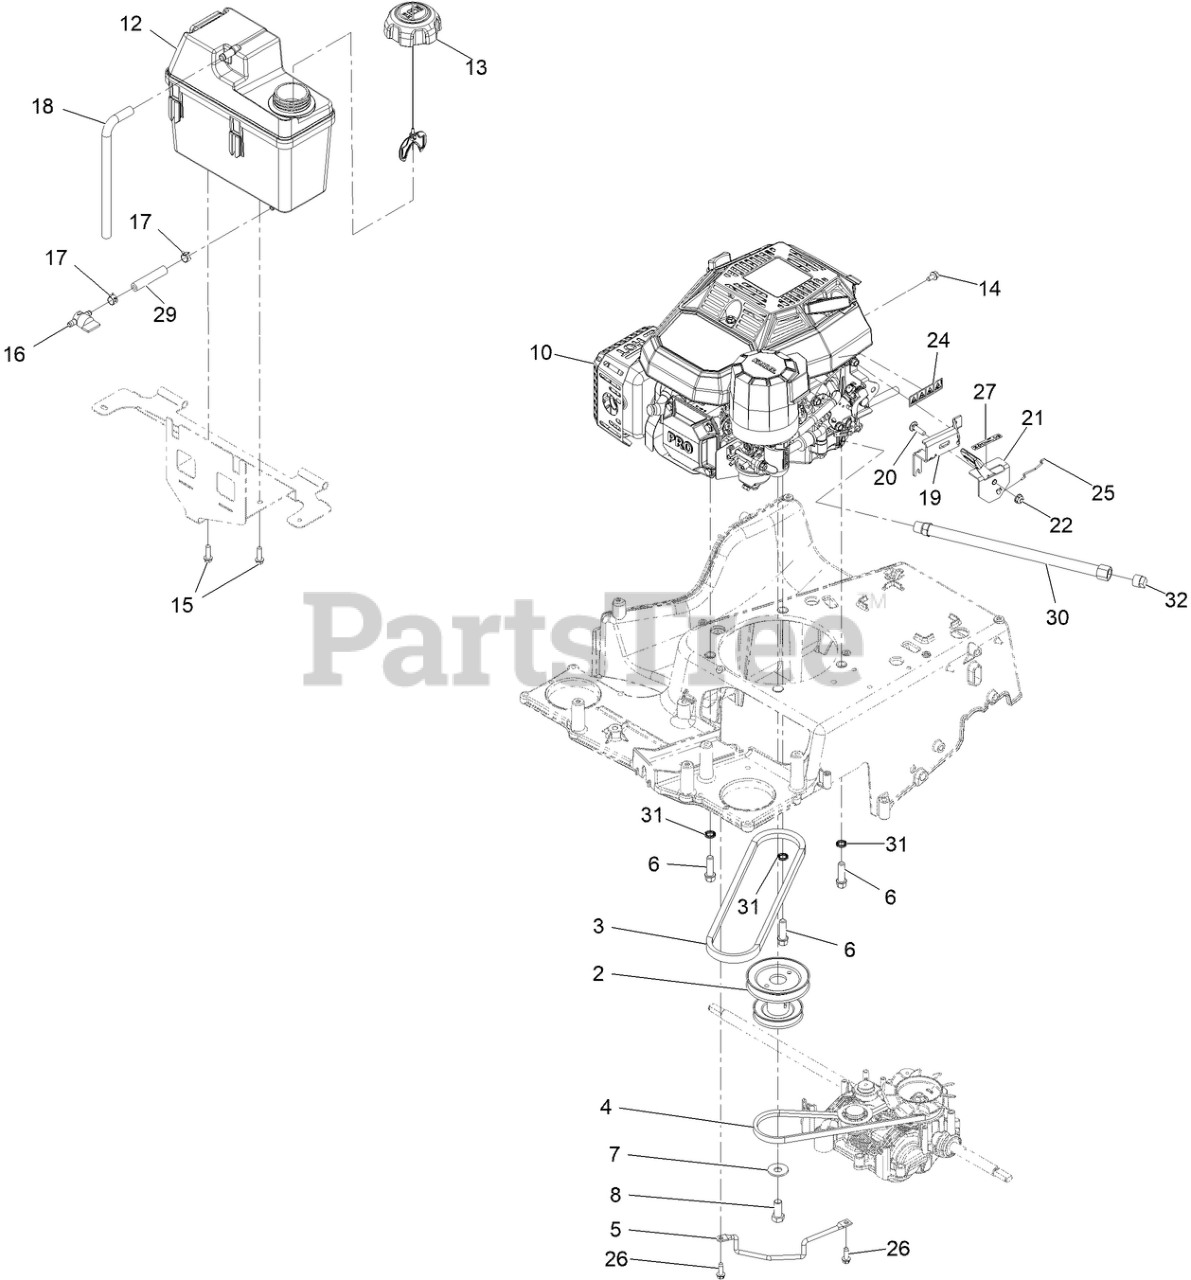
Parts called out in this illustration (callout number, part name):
2	Pulley-Engine
5	ROD-GUIDE, BELT
6	SCREW-TAPTITE
7	WASHER-BELLEVILLE
8	SCREW-HH
10	Engine-Kohler
12	TANK-FUEL
13	CAP-FUEL
14	SCREW-HWH
15	SCREW-HWH
16	VALVE-FUEL
17	CLAMP-HOSE
18	HOSE-VENT, CANISTER
19	BRACKET-THROTTLE
20	SCREW-CARR
21	CONTROL-THROTTLE
24	DECAL-WARNING, ENGINE
25	Wire-Link
26	SCREW-HWHTF
27	DECAL-THROTTLE, CHOKE
29	HOSE-FUEL
30	HOSE-DRAIN, OIL
31	WASHER-LOCK
32	PLUG-PIPE, SQH
